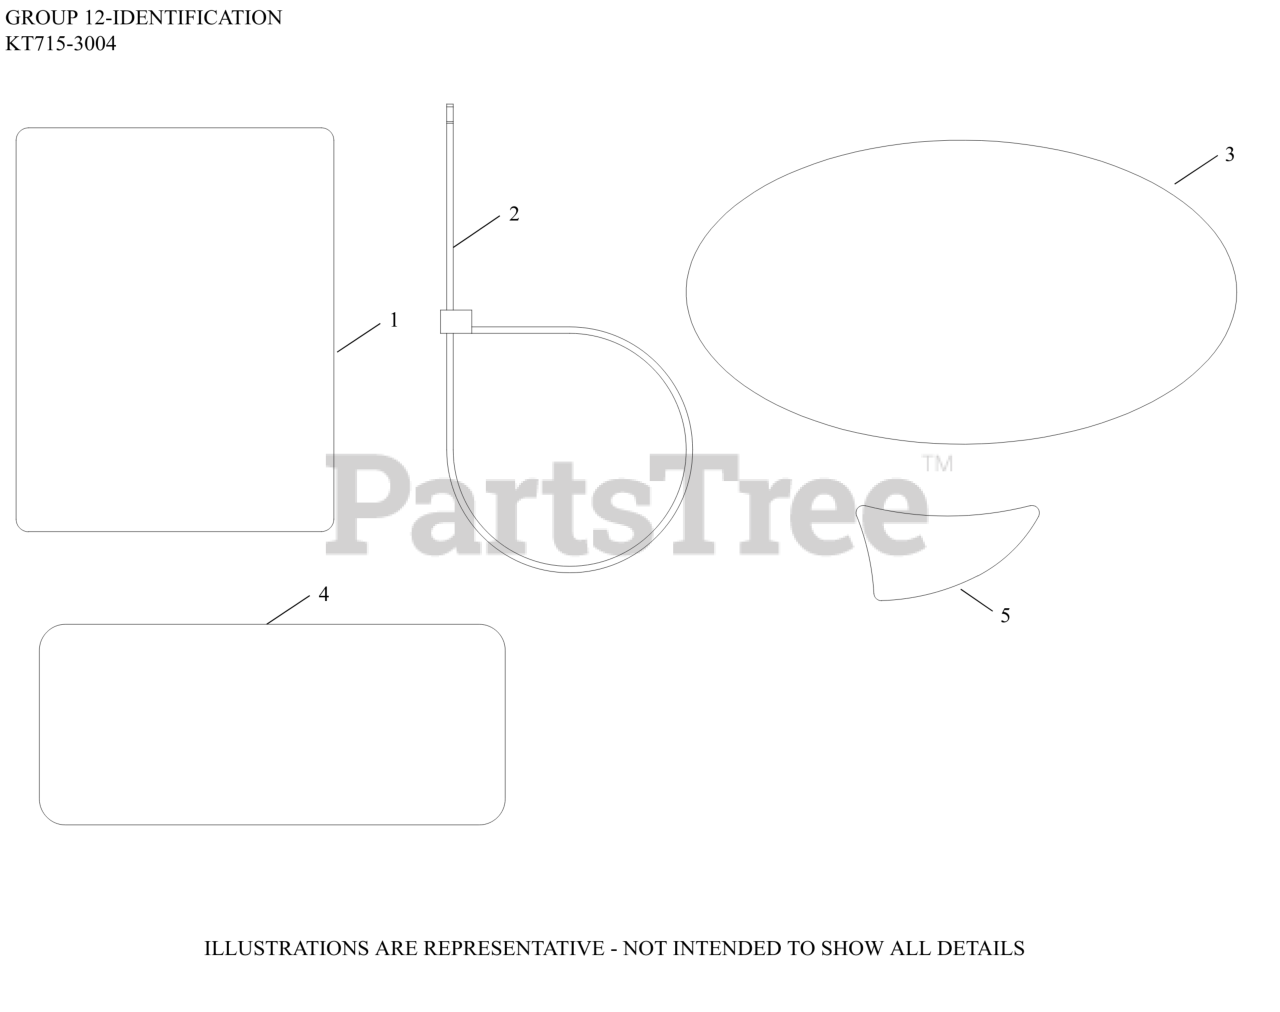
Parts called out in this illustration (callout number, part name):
1	LABEL, CLEAR LAMINATION
3	LABEL, 20HP
4	LABEL, CANADIAN COMPLIANCE
5	LABEL, SMART CHOKE
